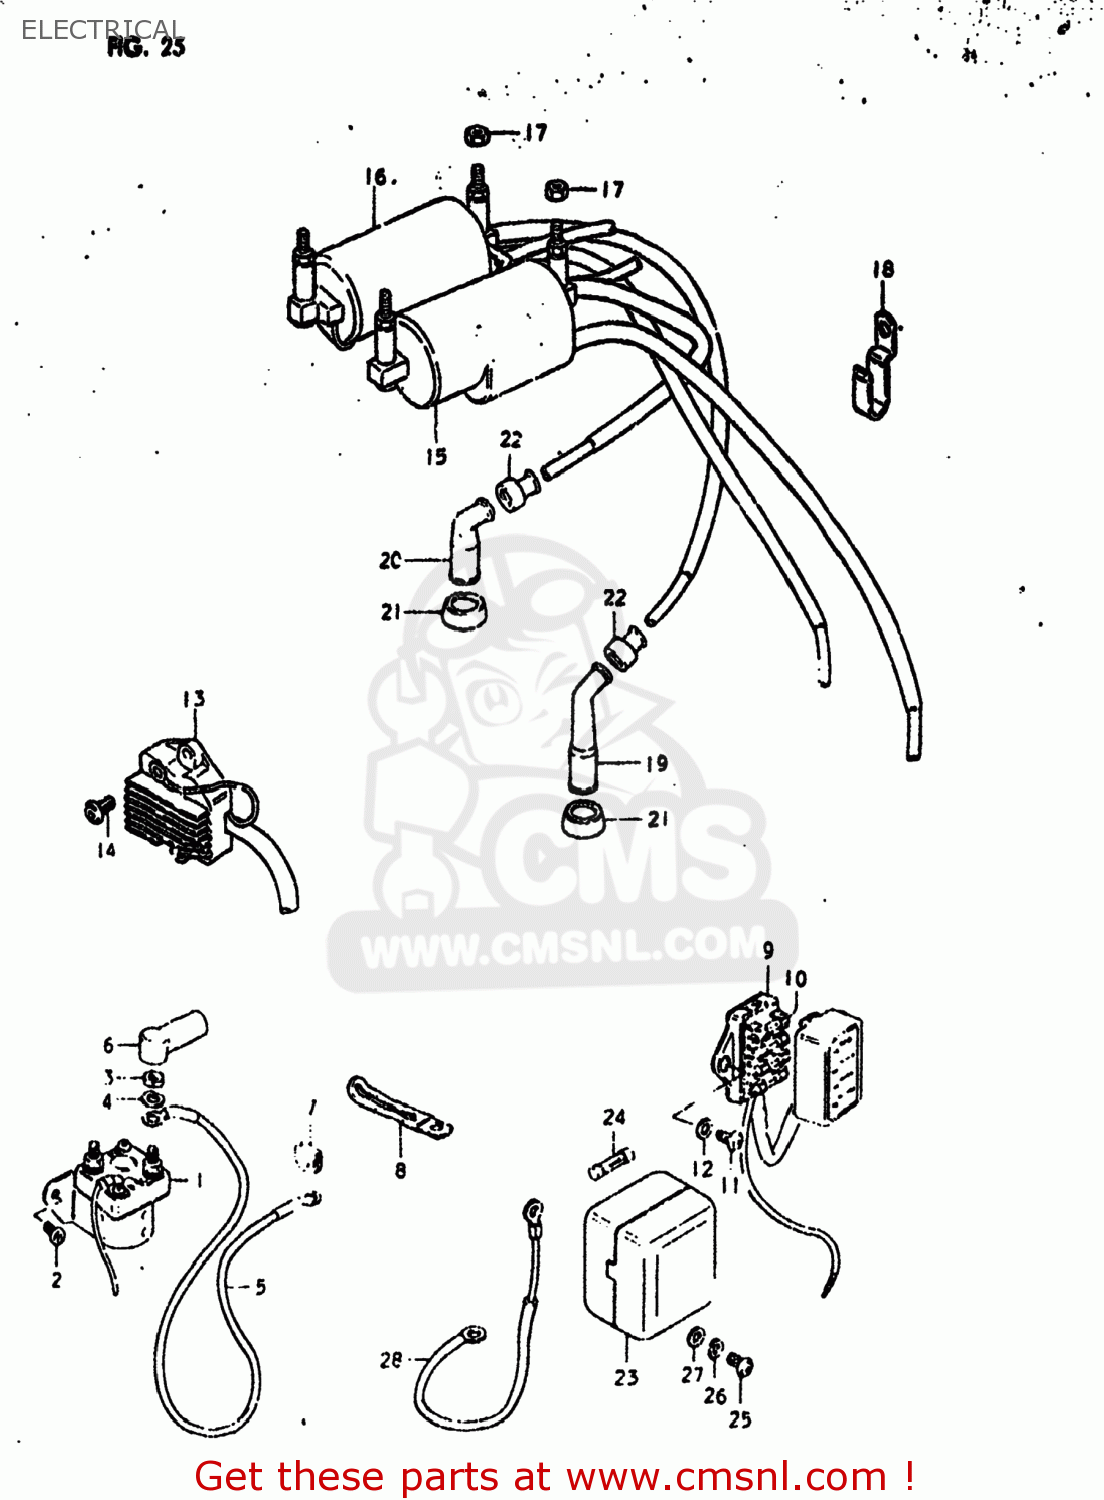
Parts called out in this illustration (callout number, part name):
1	RELAY ASSY,STARTING MOTOR
2	SCREW
3	NUT 6MM
4	LOCK WASHER
5	WIRE,STARTER MOTOR LEAD
6	CAP,STARTER RELAY
7	GROMMET,STARTER CABLE
8	CLAMP
9	BOX ASSEMBLY,FUSE
10	FUSE(15A)
11	SCREW 6X12
12	WASHER
13	RECTIFIER ASSEMBLY
14	SCREW
15	COIL ASSEMBLY,IGNITION
16	COIL ASSEMBLY,IGNITION
17	NUT
18	CLAMP
19	CAP ASSY,SPARK PLUG
20	CAP,SPARK PLUG
21	SEAL,SPARK PLUG
22	SEAL,SPARK PLU
23	TERMINAL ASSEMBLY,POWER SO
24	FUSE(10A)
25	SCREW
26	LOCK WASHER
27	WASHER
28	WIRE,POWER SOURCE LEAD
